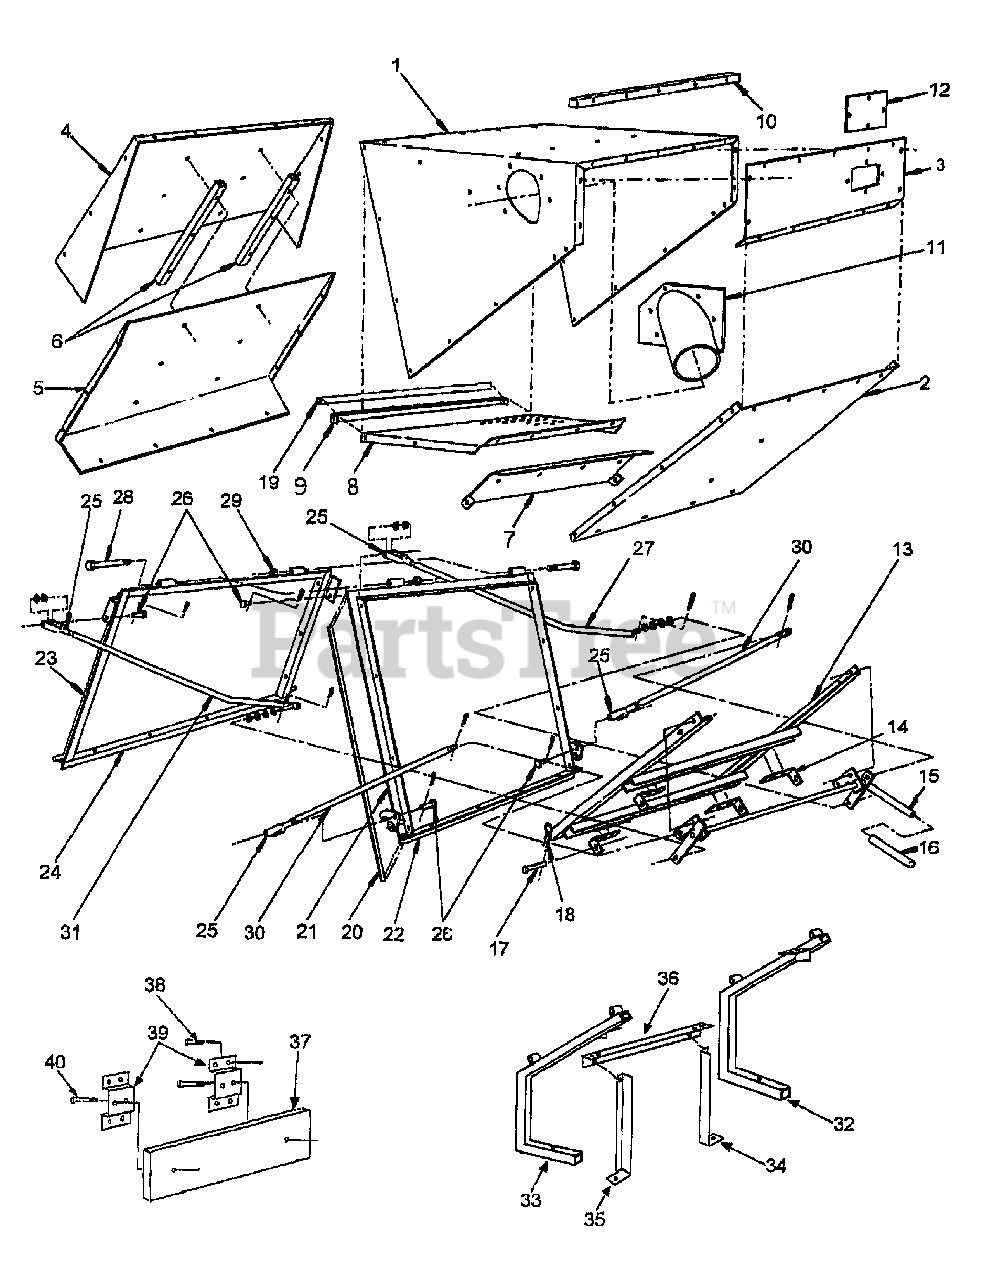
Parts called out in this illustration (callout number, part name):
1	CATCHER BODY
2	CATCHER BOX BOTTOM
3	CATCHER FRONT
4	OUTER DOOR SHELL
5	INNER DOOR SHELL
6	DOOR VENT TUBING
7	INTAKE DEFLECTOR
9	REAR SCREEN SUPPORT
10	FRONT BUMPER
11	INTAKE TUBE 6"
12	VIEWING WINDOW
13	CATCHER FRAME BASE
14	BASE FRAME TAB
15	LEVER DUMP ASSEMBLY
16	VINYL GRIP 5
17	CLEVIS PIN 1/2" X 3"
18	HAIR SPRING COTTER #6
19	RUBBER SEAL
21	CATCHER FRAME OPENING
22	BOTTOM CATCHER FRAME OPENING
23	CATCHER DOOR FRAME
24	BOTTOM DOOR FRAME
25	ADJUSTABLE YOKE END 3/8" -24
26	CLEVIS PIN 3/8" X 1-1/8"
27	HINGE ROD LF
28	1/2" X 5" HEX HEAD BOLT
29	1/2"- 13 NYLOCK NUT
31	HINGE ROD RT
32	LEFT CATCHER MOUNTING FRAME
33	RIGHT CATCHER MOUNTING FRAME
34	RIGHT CATCHER FRAME SUPPORT
35	LEFT CATCHER FRAME SUPPORT
36	CATCHER MOUNTING FRAME CROSS BAR
37	WEIGHT BAR
38	5/16" -18 x 1 CARRIAGE BOLT
39	WEIGHT MOUNTING BRACKET
40	3/8" x 4.5" x 16 HEX HEAD BOLT
